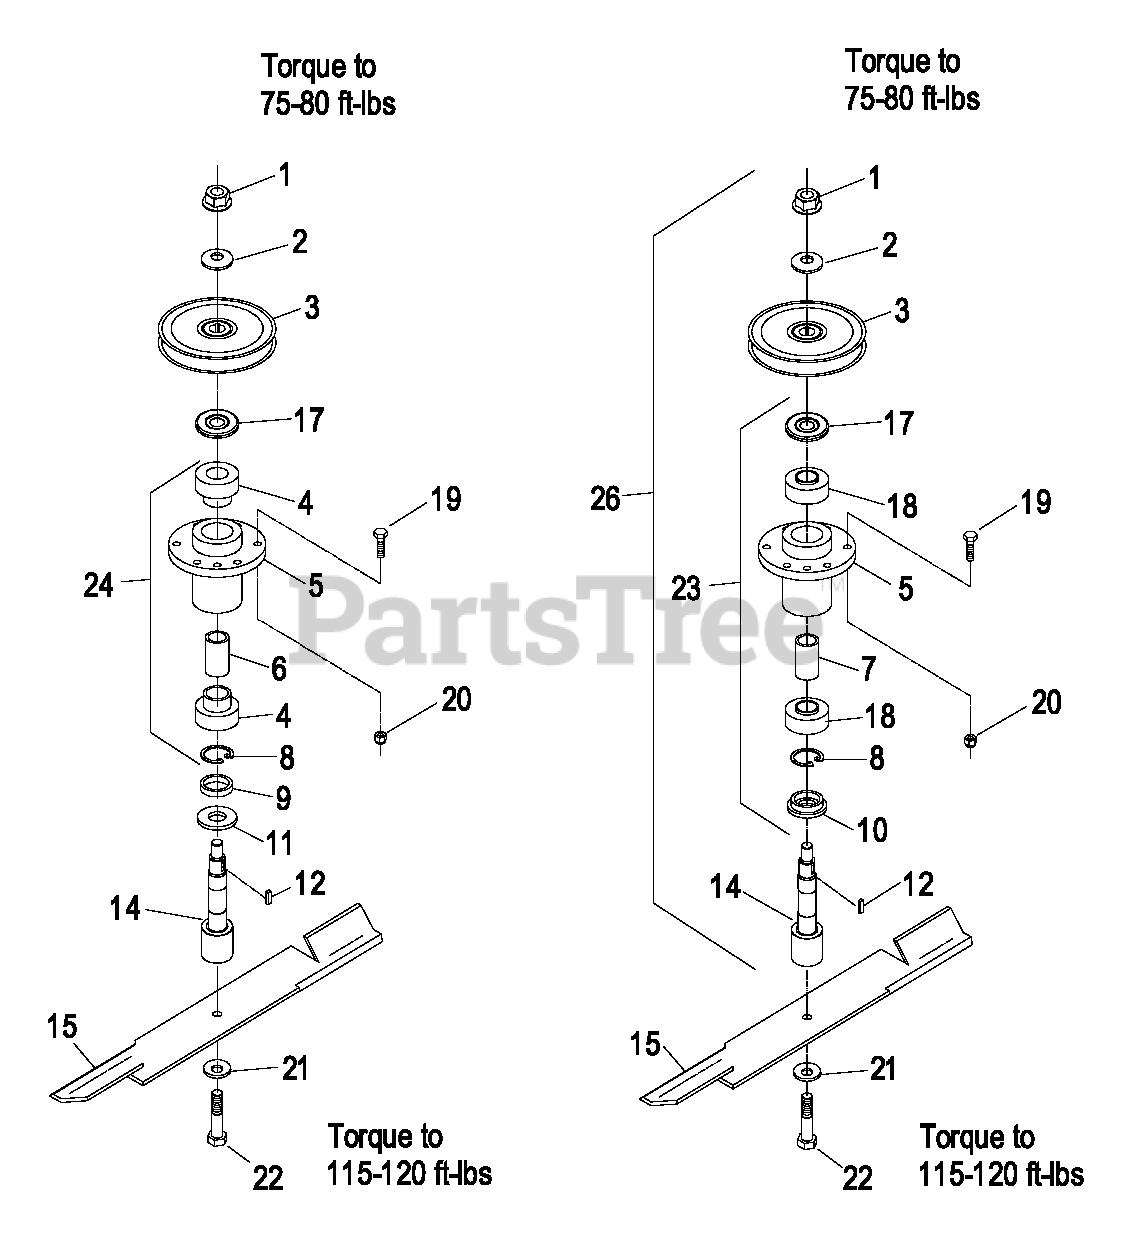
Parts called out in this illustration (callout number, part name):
1	NUT FLANGE
2	WASHER-SPRING
3	SHEAVE,BLADE DRIVE
4	BEARING
6	SPACER-BEARING
7	SPACER-BEARING
8	RING-SNAP
9	SPACER-PULLEY/BEARING
10	SPACER-GUARD, BOTTOM
11	GUARD-BEARING, BOTTOM
12	KEY-WOODRUFF
14	SHAFT,SPINDLE SHORT
16	SHEAVE,MOWER DRIVE
17	GUARD,BEARING TOP .880
18	BEARING-JACKSHAFT
19	SCREW-HH
20	NUT-LOCK, NI
21	WASHER-BLADE BOLT, HEAVY
22	SCREW-CAP
24	Cutter Housing Assy
25	ASM,CUTTER HSG SERVICE
26	ASM,CUTTER HSG SERVICE
